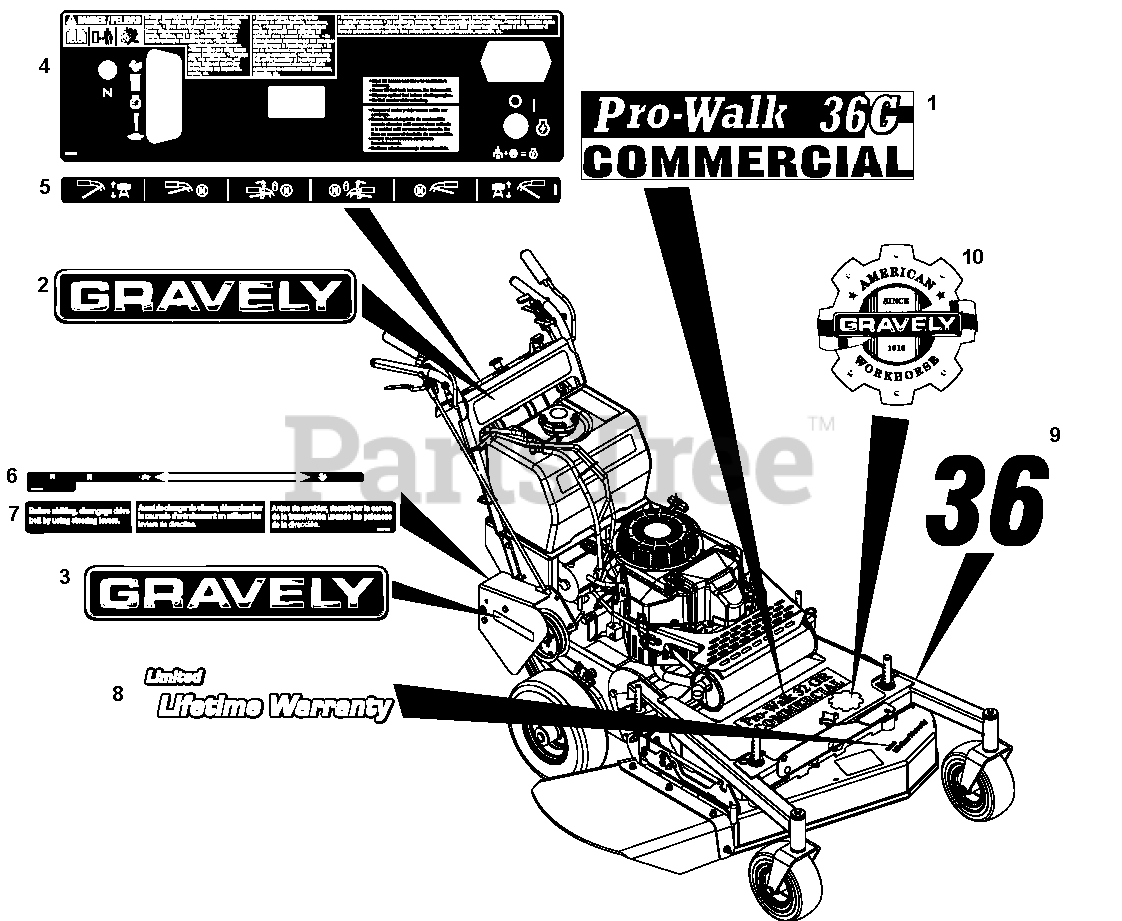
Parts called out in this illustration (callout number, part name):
1	Decal, Pro 36G (988151)
2	Decal, 15" Gravely Logo
3	Decal, 6.5" Gravely Logo
4	Decal, Console ACAO GWK
5	Decal, Steer Levers (Gear)
6	Decal, Shift Lever
7	Decal, Declutch-Gear
8	Decal, Limited Lifetime Warranty
9	Decal, Deck Size 32" (988150)
10	Decal, Gravely Heritage - Large
